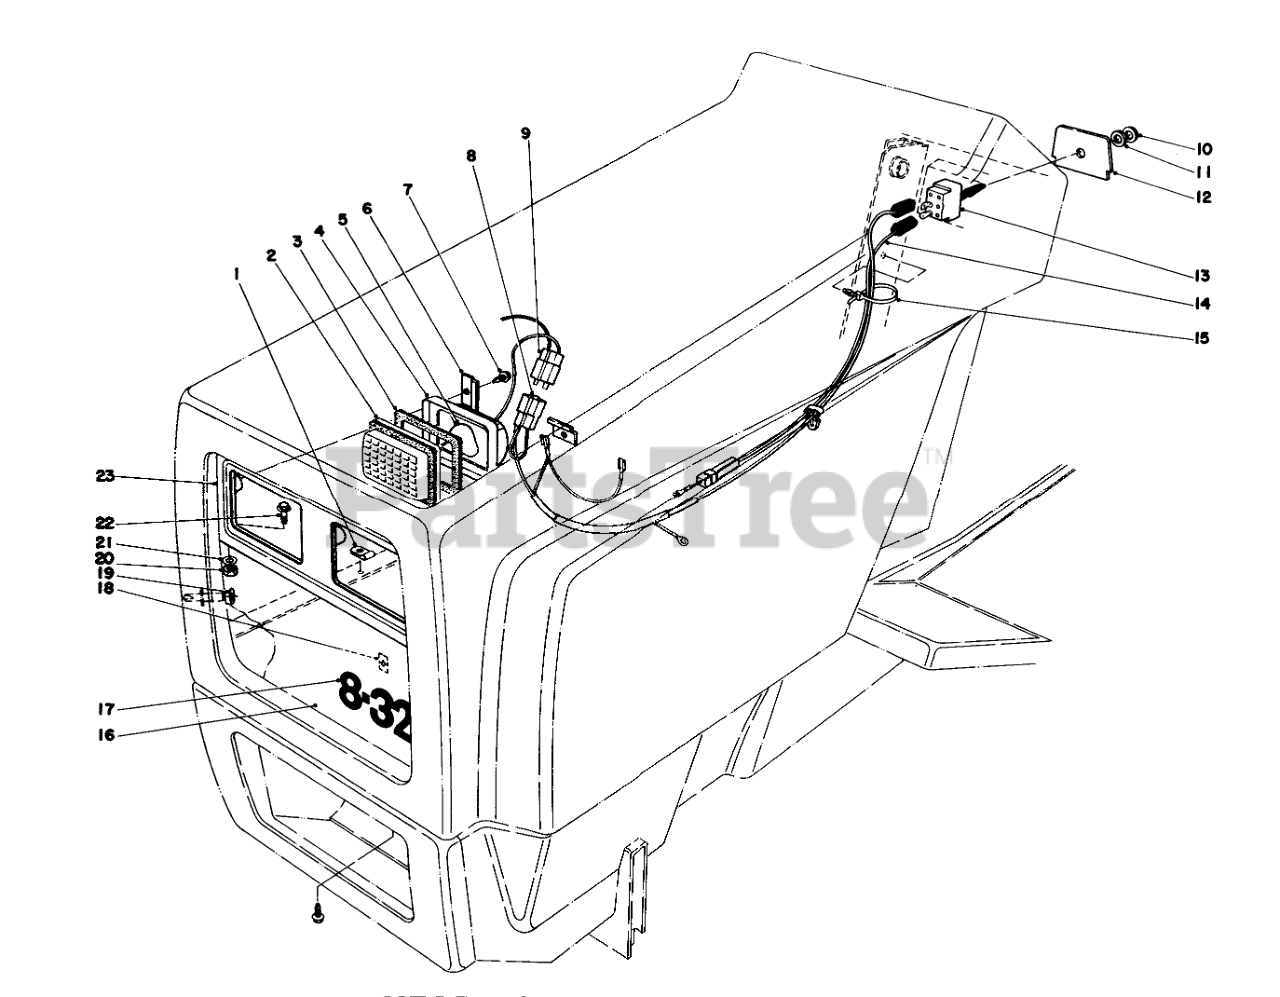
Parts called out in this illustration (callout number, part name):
1	CABLE CLAMP
2	Lens
3	Gasket Lens
4	Reflector
6	HEADLIGHT CLAMP
7	SCREW-HWHTF
8	CONNECTOR BODY
9	SOCKET
10	NUT-BULB
11	NUT-LOCK
12	DASH PANEL INSERT
13	LIGHT SWITCH
14	WIRE HARNESS
15	TIE-CABLE
16	Grille Headlight
17	Nameplate Grille
19	WASHER
20	NUT-LOCK, SIDE
21	WASHER-FLAT
22	SCREW-SHWH
23	HEADLIGHT PANEL B
